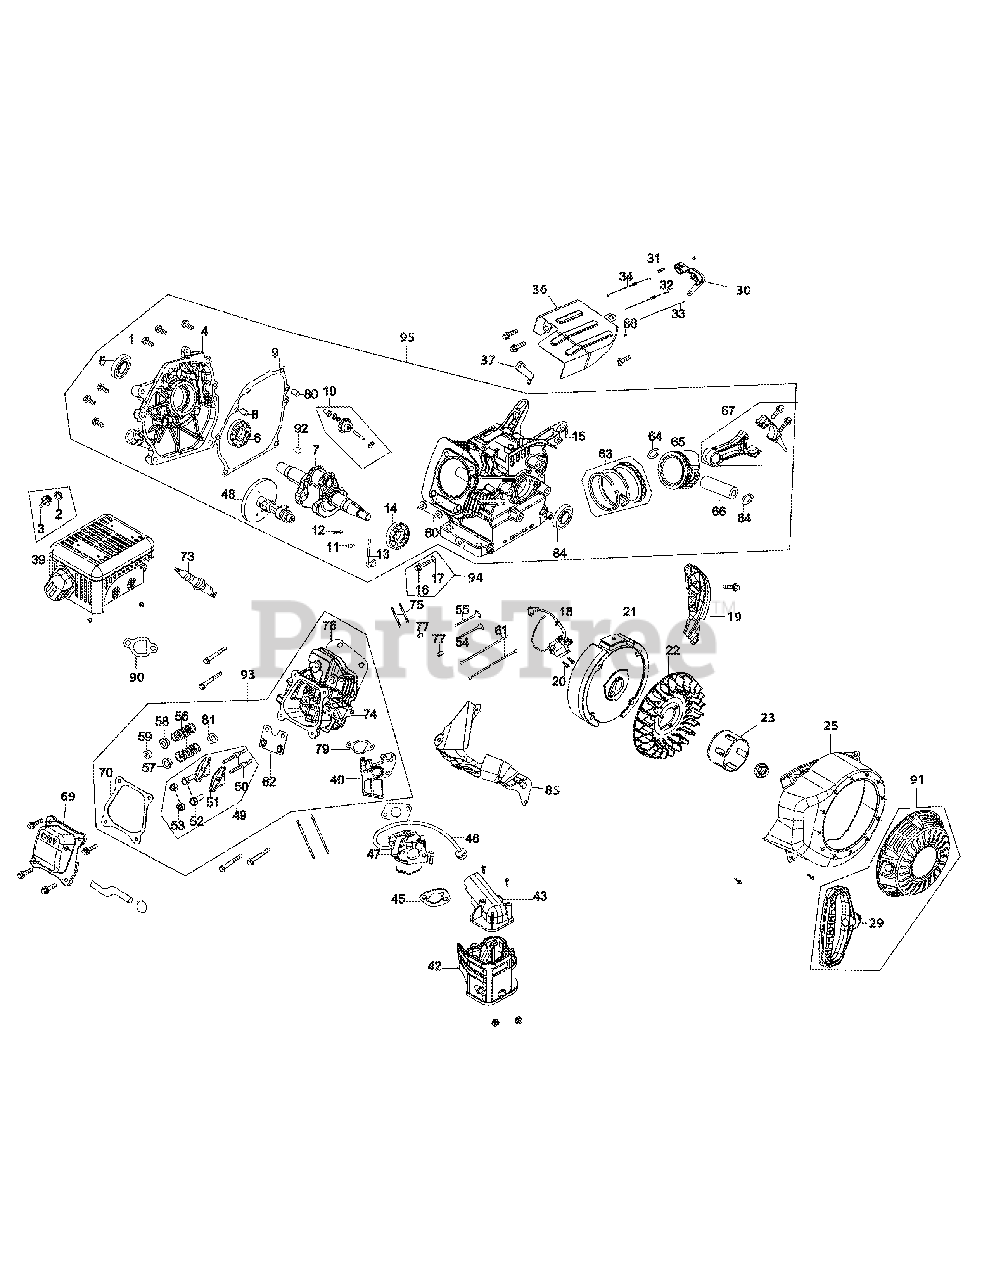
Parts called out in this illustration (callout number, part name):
1	Bolt
2	Dipstick Assembly
2	O-Ring Dipstick
2	O-Ring
3	Dipstick Assembly
4	Crankcase Cover
5	Oil Seal
6	Bearing
7	Crankshaft Assembly
8	Dowel Pin
9	Case Cover Gasket
9	Crankcase Cover Gasket
10	Governor Assembly
11	O-Ring Gov. Shaft
11	O-Ring, 5.2 x 1.9
12	Pin Lock
13	Governor Arm Shaft
14	Bearing
15	Crankcase Complete
16	Oil Drain Plug and Washer Assembly
16	Oil Drain Plug
17	Oil Drain Plug Washer
17	Washer, 10 x 16 x 1.5
18	Ignition Coil
19	Flywheel Baffle
21	Flywheel
22	Cooling Fan
23	Starter Cup
25	Fan Cover
29	Recoil Starter Handle
30	Governor Arm Bracket
32	Throttle Return Spring
33	Governor Rod
34	Governor Return Spring
36	Cover Shield
37	Governor Spring Bracket
39	Muffler Assembly
40	Carburetor Insulator Plate
40	Carburetor Insulator
41	Nut
42	Intake Heater Box Base
43	Intake Heater Box
45	Heat Pipe Intake Gasket
45	Carburetor Gasket
46	Primer
47	Carburetor Assembly
48	Camshaft Assembly
49	Rocker Arm & Bolt Assembly (Incl. 50-53)
50	Pivot Bolt
51	Rocker Arm
52	Valve Adjusting Nut
53	Pivot Locking Nut
54	Valve Kit
56	Valve Spring
57	Intake Valve Spring Seat
58	Exhaust Valve Spring Seat
59	Exhaust Valve Adjuster
60	Valve Lifter
61	Push Rod Kit
62	Push Rod Guide Plate
63	Piston Ring Set - OIL
64	Piston Pin Clip
65	Piston
66	Piston Pin
67	Connecting Rod Complete
69	Valve Cover
70	Valve Cover Gasket
73	Spark Plug
74	Cylinder Head - Complete
75	Muffler Stud Assembly
76	Cylinder Head Gasket (graphite)
76	Cylinder Head Gasket
77	Dowel Pin 10x16
79	Carburetor Insulator Plate Gasket
79	Carburetor Insulator Gasket
80	Dowel Pin
81	Packing
84	Oil Seal
84	Oil Seal, 22 x 35 x 7
85	Side Plate
90	Muffler Gasket
91	Recoil Starter Assembly
92	Flywheel Key
93	Cylinder Head Assembly
94	Oil Drain Plug and Washer Assembly
95	Short Block Assembly
